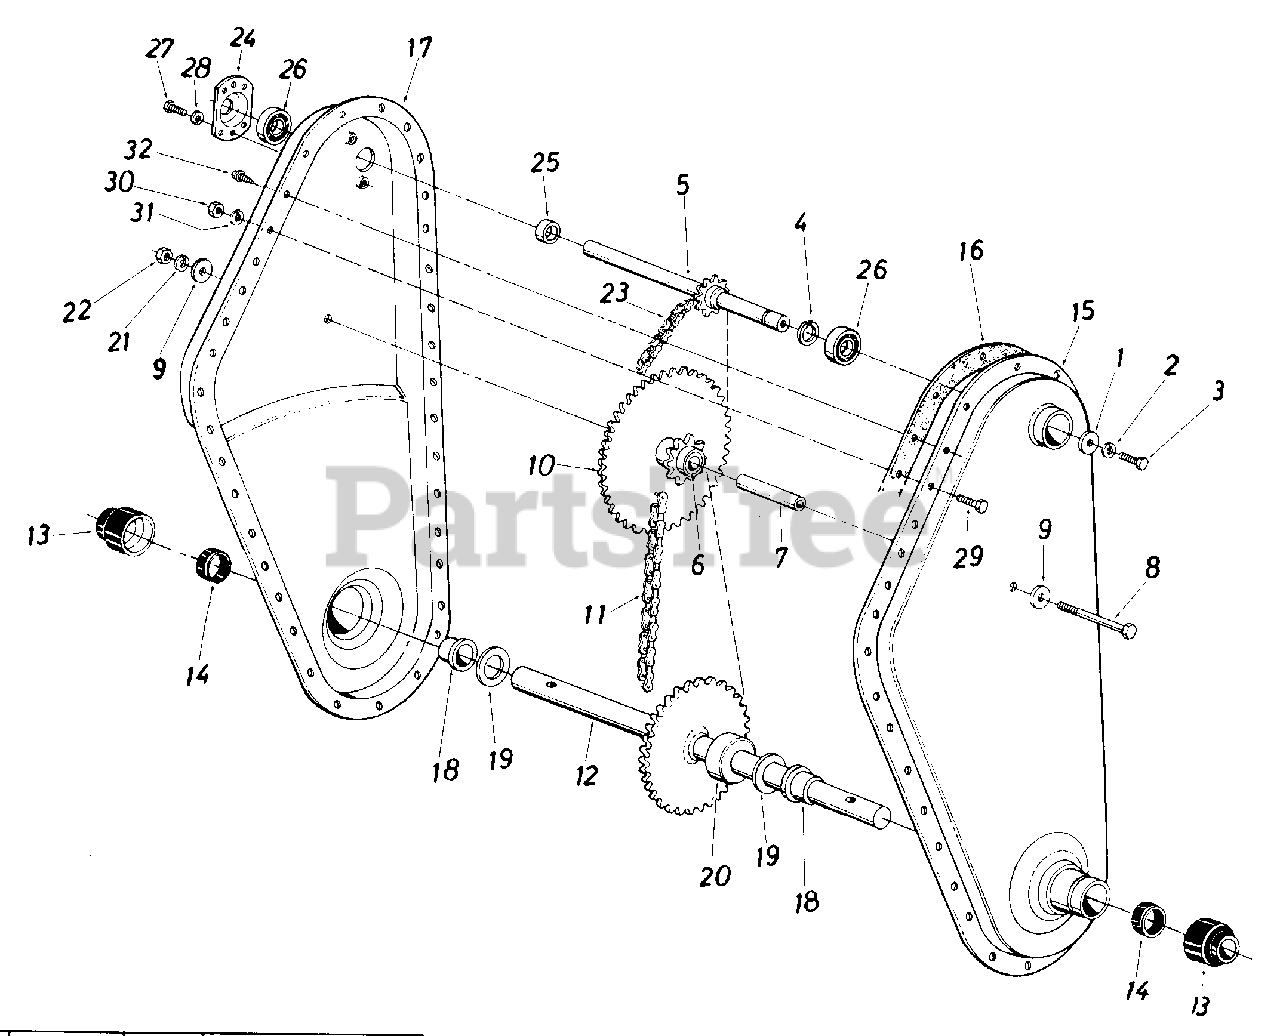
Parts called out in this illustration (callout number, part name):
1	WASHER-FL
2	LOCK WASHER 1/4 DIA
3	BOLT - 1/4-28 X 5/8 61.5
4	RING-SNAP
5	SHAFT-INPUT
7	HUB-SPROCKET
8	SCREW-HEX 3/8-16 X 2.75
9	WASHER-FL-.385 X 1.00 X .135
10	SPROCKET ASSY-8T & 40T
11	#50 CHAIN 5/8 PITCH X 46 LINKS E
12	SHAFT ASSY-TINE
13	CAP-DUST
19	WASHER-FL-1.03 ID X 1.62 X .03 HD
20	SPACER
21	WASHER-LOCK-3/8
22	NUT-HEX JAM 3/8X24
23	#35 CHAIN 3/8 PITCH X 52 LINKS E
24	HOUSING-BRG
26	BEARING-BALL
27	SCREW-HEX WASH SF TAPP
28	LOCK WASHER 1/4 DIA
29	SCREW-HEX 5/16-18 X .75
30	NUT-HEX 5/16-18
31	WASHER-LOCK-5/16
32	SCREW-HEX WASH SF TAPP
